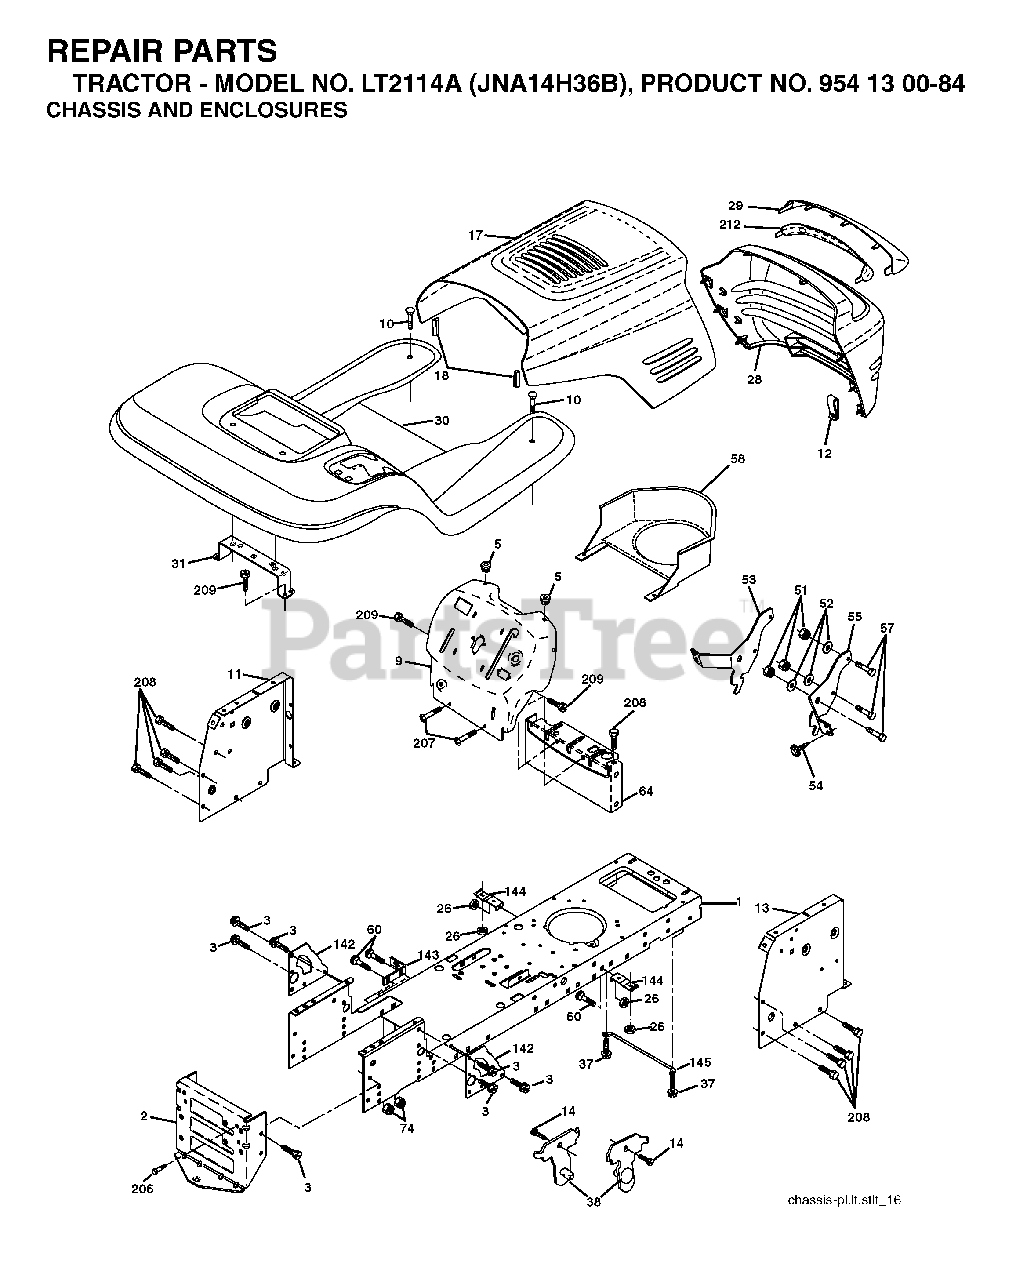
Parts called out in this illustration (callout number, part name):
1	CHASSIS STAMPING
2	DRAWBAR, 12GA
3	SCREW 3/8-16X3/4
5	BUMPER.RUBBER.HOOD
10	BOLT D
11	PANEL.DASH.LH.LTX
13	PANEL DASH RH
18	BUMPER.HOOD.LARGE.1.75"
26	NUT
28	GRILL/LENS ASM.
38	BRACKET.ASM.PIVOT.MOWER.REAR
51	LOCKNUT
53	BRACKET.GRILLE.LH
57	BOLT
58	AIR DUCT P/L/LT
64	DASH LOWER
74	LOCKNUT
142	PLATE REINFORCEMENT
143	BRACKET, SWAY BAR
144	BRKT, FOOT REST
145	ROD PIVOT CHASSIS/HOOD
206	SHOULDER BOLT 5/16-18TT
207	SCREW, 5/16-18 X 1/2
208	SCREW 3/8-16X1/2
209	SCREW, 3/8-16X3/4
